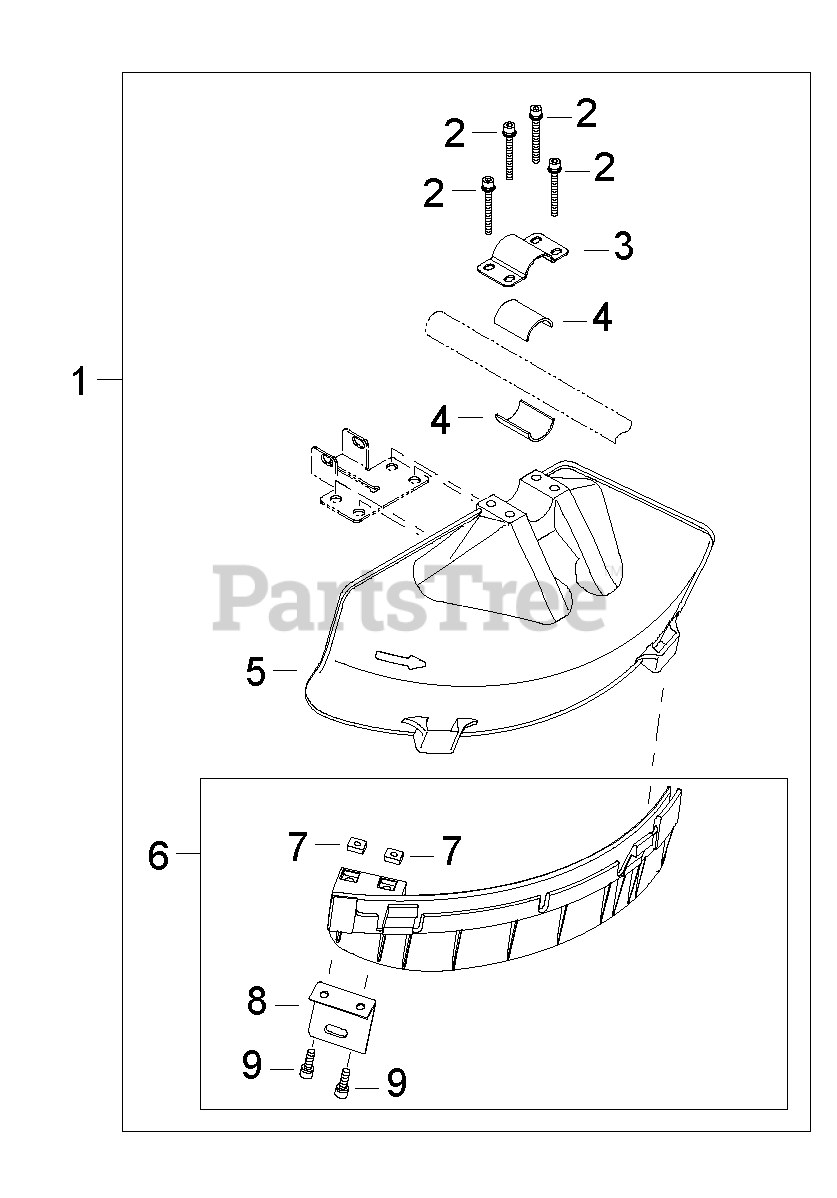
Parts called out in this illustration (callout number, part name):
1	DEBRIS SHIELD KIT
2	SCREW - 5X45
3	CLAMP - UPPER
4	SPACER
5	SHIELD, DEBRIS
6	SHIELD GUARD KIT
7	NUT - 5
8	KNIFE, TRIMMER LINE
9	SCREW - 5X16
